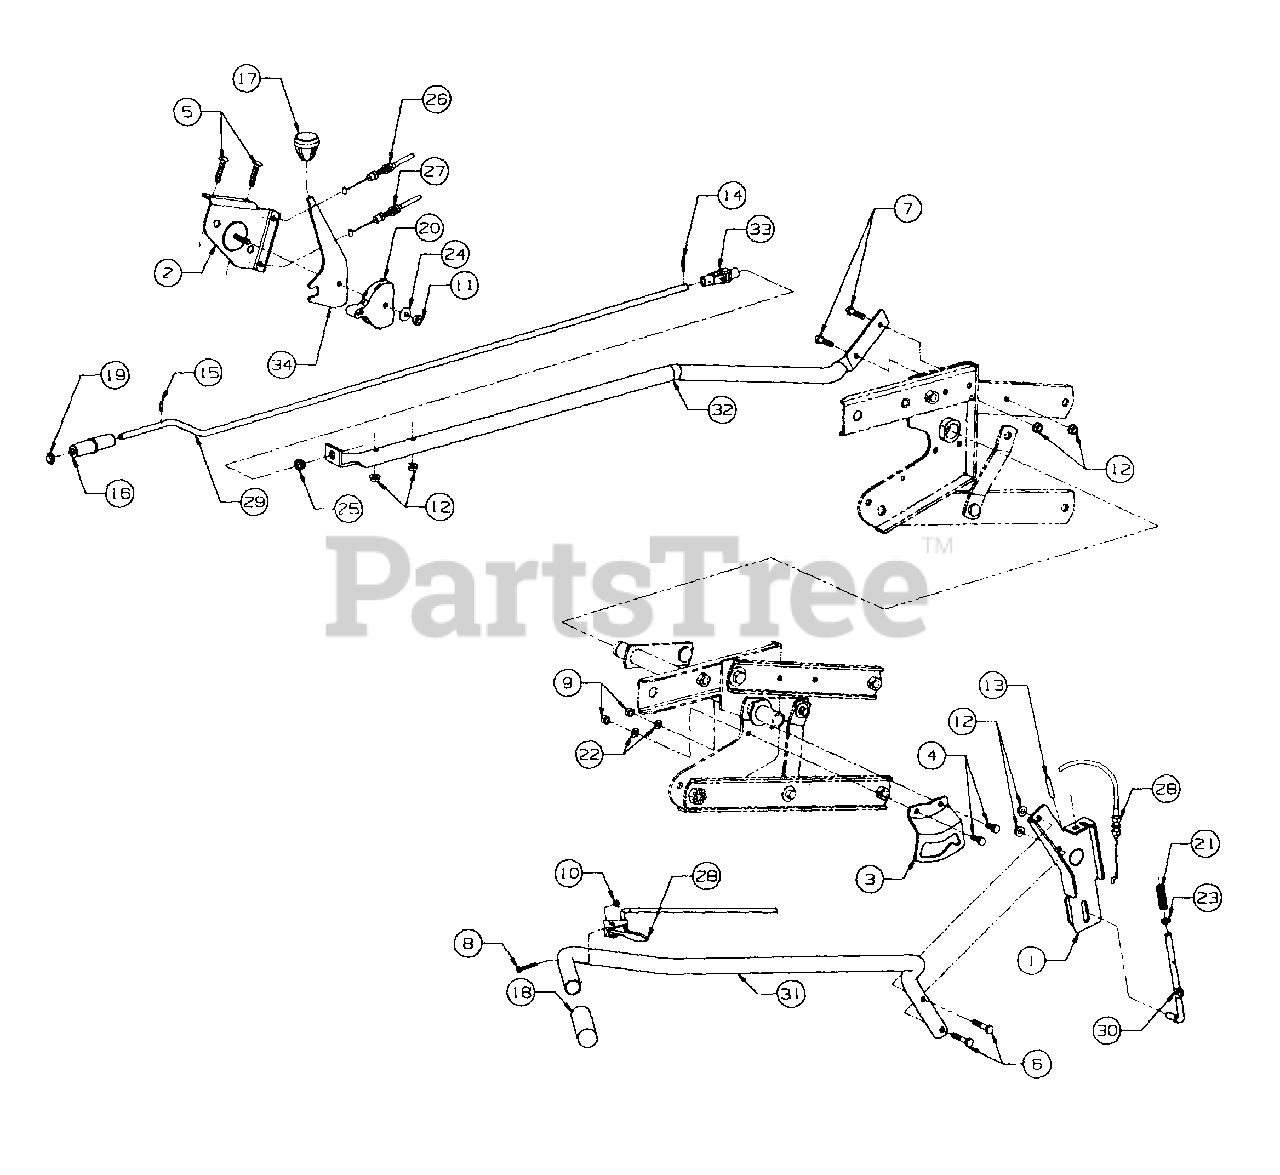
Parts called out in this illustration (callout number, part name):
3	Bracket, Lift Handle Latch
4	Screw, Hex Cap, 5/16-24 X .75 Lg GR5
5	Bolt, Carriage, 5/16-18 X 1.50 Lg
6	Screw, Hex Cap, 5/16-18 X 1.50 Lg GR2
7	Screw, Hex Cap, 5/16-18 X 1.25 Lg
8	Screw, Oval c/sunk, 410-24 X 1.36 Lg
9	Nut, Hex, 5/16-24
10	Nut, Flat, #10-24
11	Nut, Hex Center Lock, 5/16-18
12	Nut, Hex Flange Top Lock, 5/16-18
13	Pin, Spiral Spring, 1/4 Dia X 1.50 Lg
14	Pin, Spiral Spring, 1/8 Dia X .812 Lg
15	Pin, Roll Spring, 1/8 Dia X .63 Lg
16	Knob, Chute Crank
17	Knob, Tilt Handle
19	Cap, Push
20	Guide, Cable
21	Spring, Compression
22	Washer, Lock, 5/16
23	Washer, Flat, .385 X .62 X .063 Thk
24	Washer, Bell, .345 X .88 X .060 Thk
25	Bushing, Plastic
26	Cable, Chute Control
27	Cable w/Clip, Chute Control
28	Cable, Lift Latch
29	Rod, Chute Crank
30	Rod, Lift Latch
